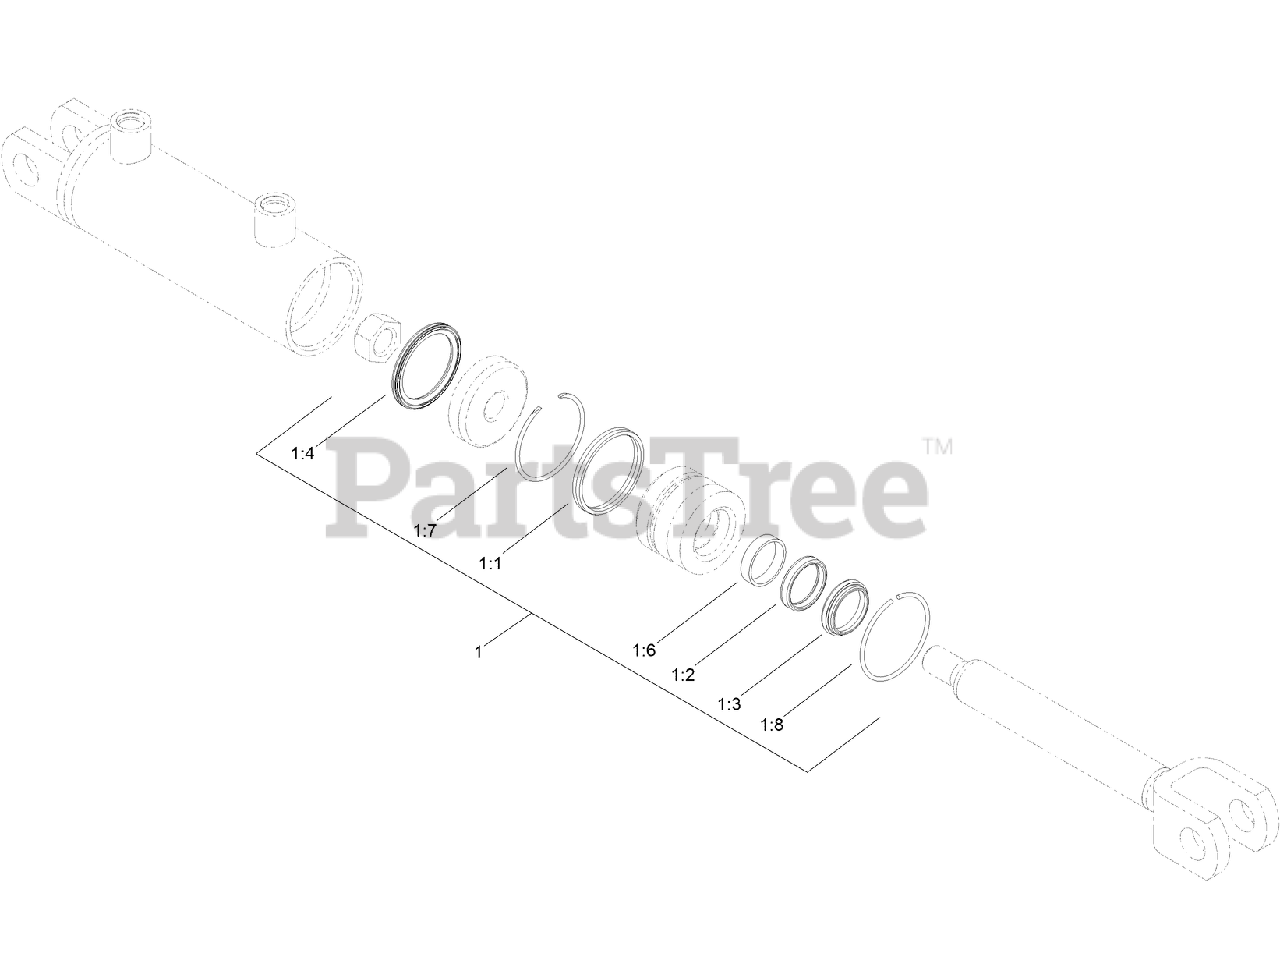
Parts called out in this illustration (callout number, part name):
1	SEAL REPAIR KIT
1:1	SEAL-DUAL
1:2	Deck ASM
1:3	Deck ASM
1:4	Deck ASM
1:6	RING-WEAR, ROD
1:7	RING-RETAINING, INTERNAL
1:8	RING-RETAINING, EXTERNAL
